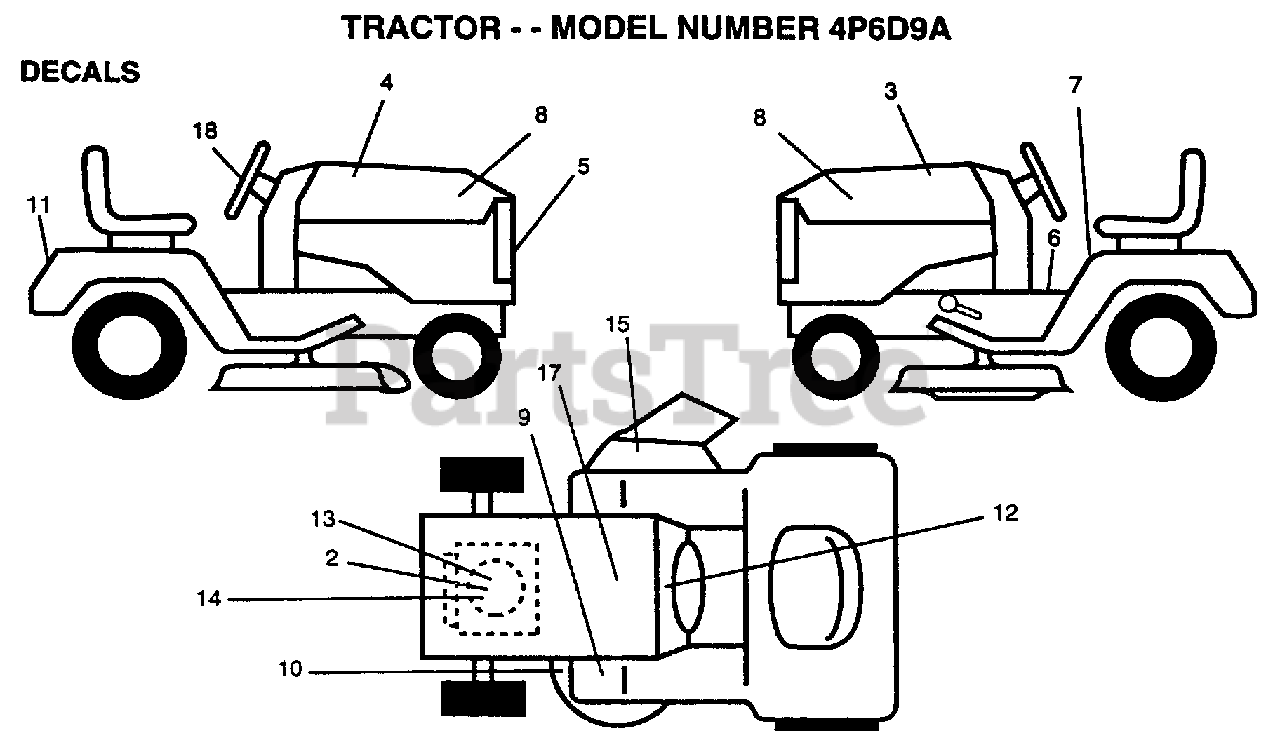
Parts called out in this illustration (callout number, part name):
2	DECAL.ENG.272757
3	DECAL.HD.LH.RALLY
4	DECAL.HD.RH.RALLY
5	GRILL DECAL
6	DECAL BRAK PARK
7	DECAL CAUTION
8	DECAL.HOOD.INSERT
9	DECAL T
10	"DECAL.V.BELT.44"""
11	FENDER DECAL
12	DECAL.DASH.INSTR.
13	DECAL.ENG.272101
15	"DECAL, WARNING"
17	DECAL
18	"DECAL,STR WHL"
